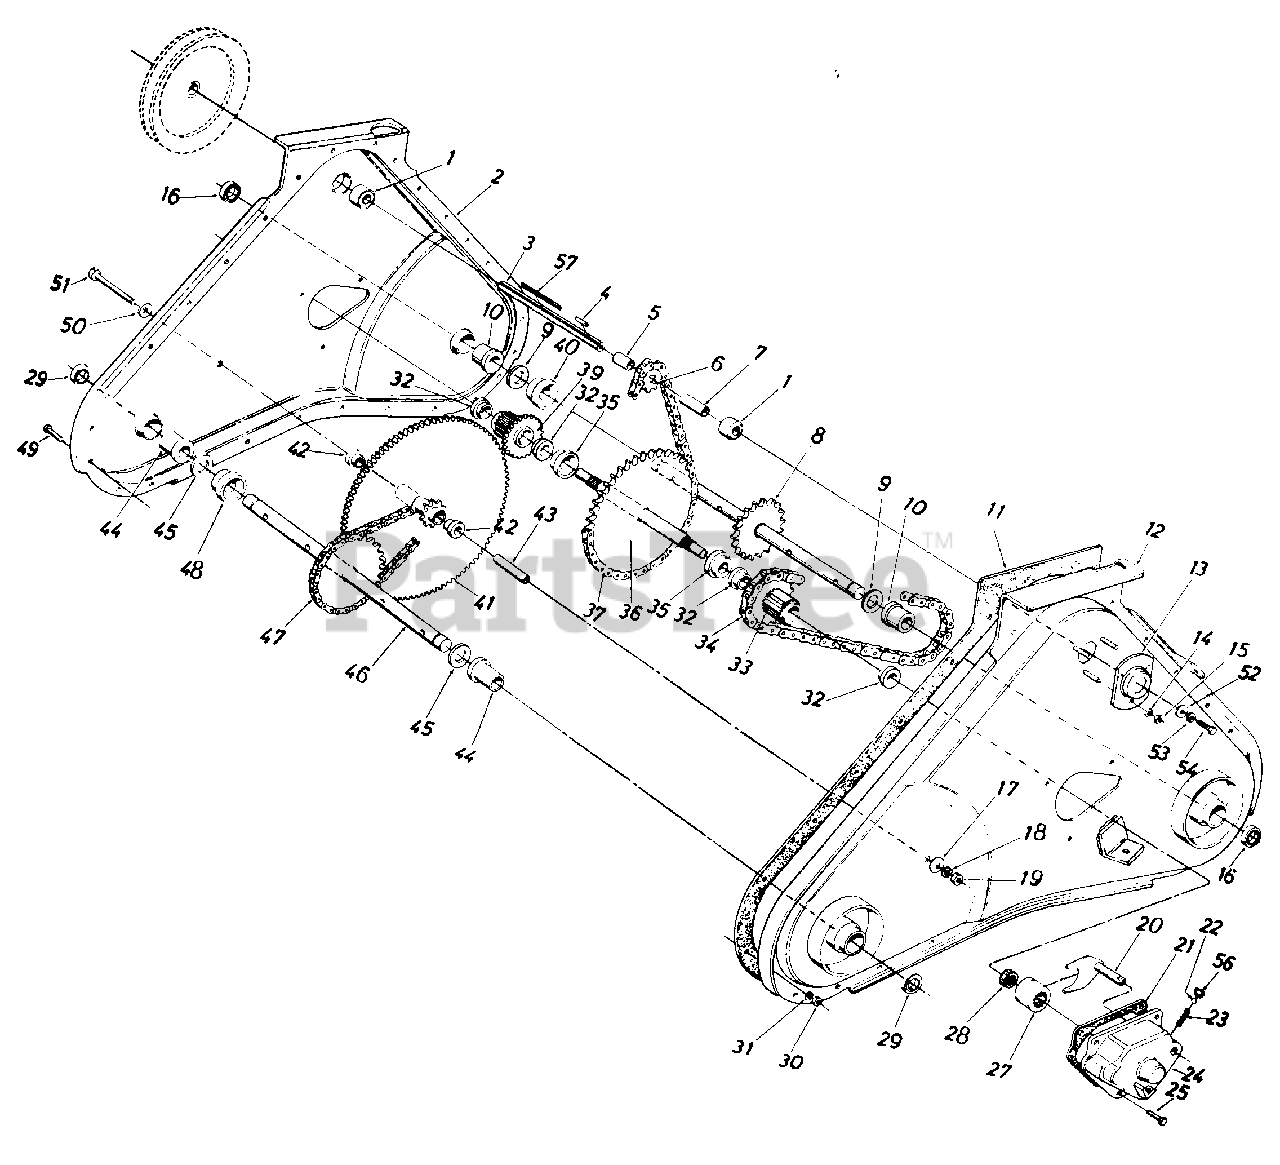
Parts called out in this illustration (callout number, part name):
1	BEARING-BALL
2	CHAIN CASE ASSY-RH
3	SHAFT-INPUT
4	KEY-SQ 3/16 X .75
6	SPROCKET-9T 5/8 SHAFT
8	SHAFT ASSY-TINE
9	WASHER-FL
10	BEARING-FLANGE
11	GASKET
12	CHAIN CASE ASSY-LH
13	HOUSING-BRG
14	LOCK WASHER 1/4 DIA
15	NUT-HEX 1/4-28
16	SEAL-OIL-1.25 SHAFT
17	WASHER-BELL .3/8ID X 1.12OD X .030
18	WASHER-LOCK-3/8
19	NUT-HEX INS L 3/8 X 24
20	YOKE-SHIFT-LH
22	BALL-DETENT
23	SPRING-DETENT FOOTE #333-19
24	HOUSING-LH
25	SCREW-HEX WASH SF TAPP
28	DOG-DRIVER
29	SEAL-OIL-DOUBLE LIP-1 IN SHAFT
30	NUT-HEX 1/4-28
31	LOCK WASHER 1/4 DIA
32	BEARING-FLANGE
33	SLEEVE ASSY-SPRKT BRG
34	#50 CHAIN 5/8 PITCH X 50 LINKS E
36	SHAFT ASSY
37	#420 CHAIN 1/2 PITCH X 58 LINKS E
39	SLEEVE ASSY-GEAR
40	SPACER-STEPPED
41	SPROCKET & GEAR ASSY
42	BEARING-FLANGE .630 ID
44	BEARING-FLANGE
45	WASHER-FL-1.00 X 1.625 X .090
46	SHAFT-AXLE
47	#420 CHAIN 1/2 PITCH X 46 LINKS E
49	SCREW-HEX 1/4-28 X .62
50	WASHER-BELL .3/8ID X 1.12OD X .030
51	SCREW-HEX 3/8-16 X 2.75
52	WASHER-FL-.344 ID X .88 OD X .063
53	WASHER-LOCK-5/16
54	SCREW-CAP LOCK 5/16-24 X .75
57	KEY-SQ 3/16 X 3/16 X 2
